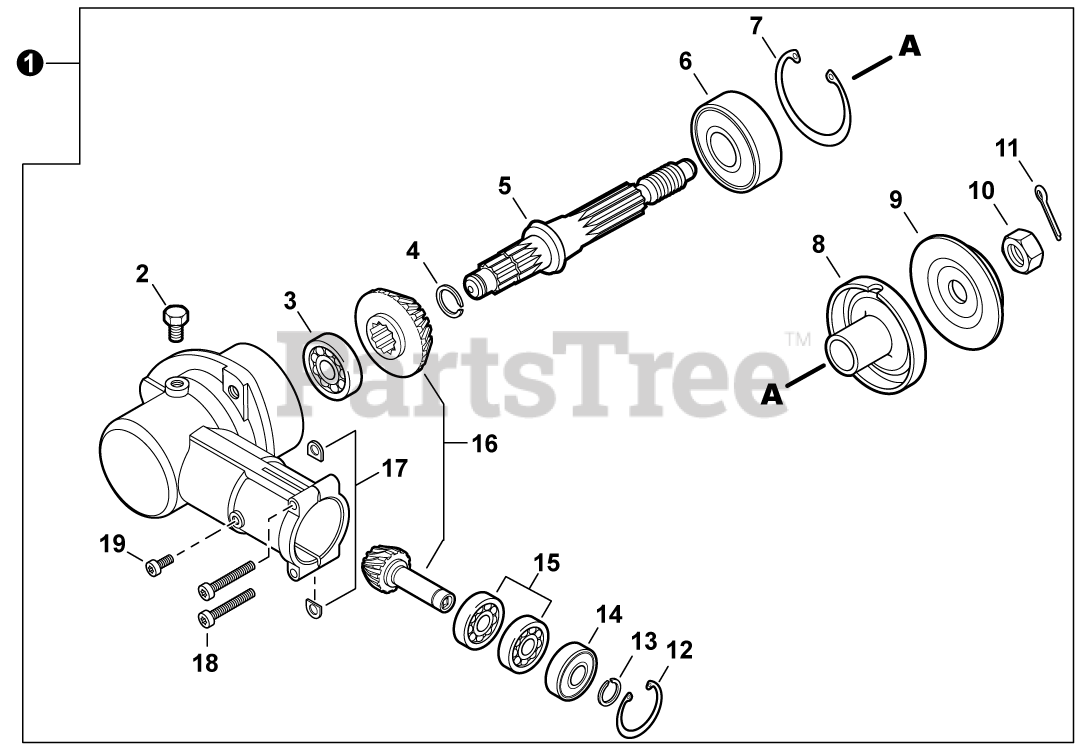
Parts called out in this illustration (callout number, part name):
1	GEAR CASE ASSY
2	BOLT M8x8
3	BEARING, BALL 629
4	RING, SNAP 12
5	SHAFT, GEAR
6	BEARING, BALL 6302
7	RING, SNAP 42
8	PLATE, ADAPTOR - UPPER
9	PLATE, ADAPTOR - LOWER
10	NUT 10x1.25 LH
11	PIN, COTTER 2x22
12	RING, SNAP 22
13	RING, SNAP 10
14	BEARING, BALL 6900Z
15	BEARING, BALL 6900
16	GEAR SET
17	D-WASHER
18	BOLT, TORX 5x25
19	BOLT, TORX 5x12
